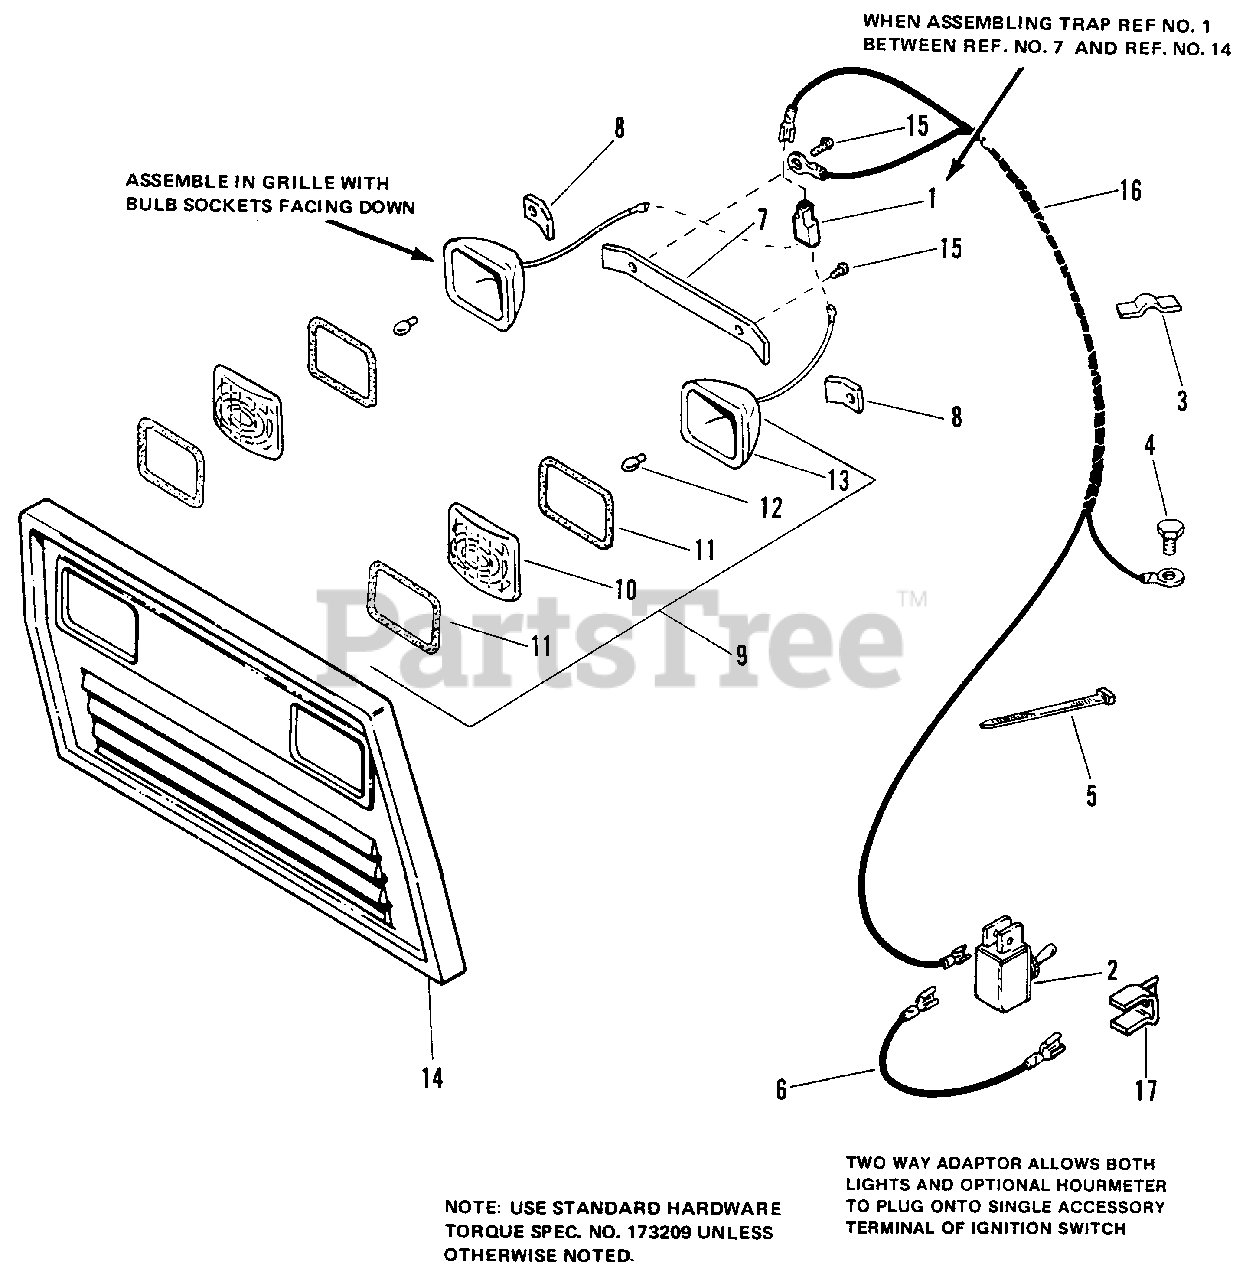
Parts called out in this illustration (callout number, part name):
1	CONNECTOR, Insulated
2	SWITCH, Toggle
3	CLIP, Wire
4	SCREW, Hex Hd., Taptite, 1/4-20 x 3/8
6	WIRE ASSEMBLY
7	CLIP, Center Headlight
8	CLIP, Side Headlight
9	LIGHT ASSEMBLY
10	LENS, Clear Plastic
11	GASKET, Lens
12	BULB
13	REFLECTOR ASSEMBLY
15	SCREW, Rd. Hd., Philips 10-32 x 3/8
16	WIRE ASSEMBLY, Headlights
17	ADAPTER, 2-Way
